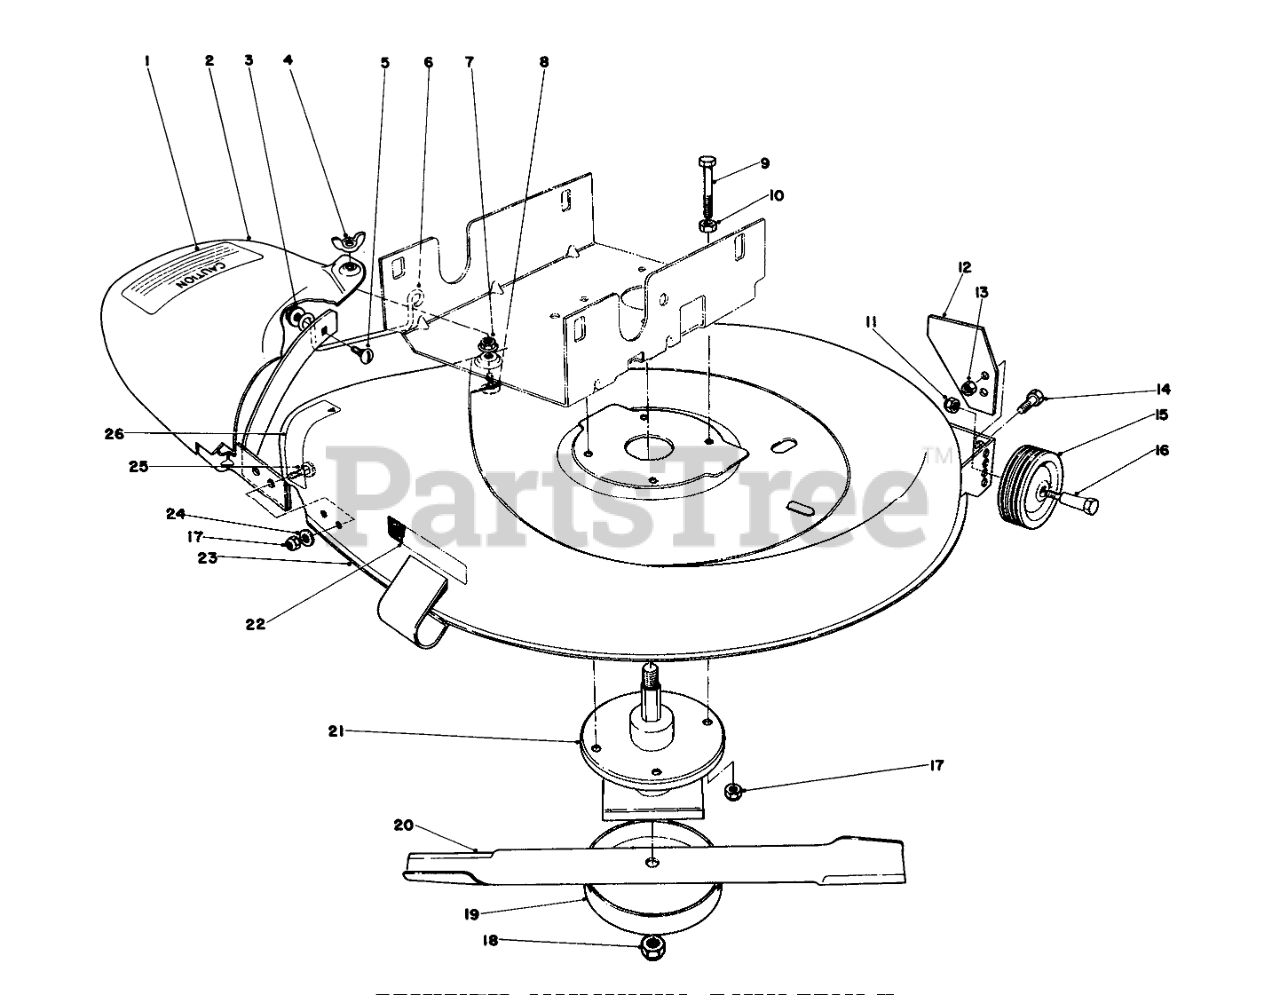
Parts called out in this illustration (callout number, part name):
1	Decal
2	DEFLECTOR WA R
3	NUT-LOCK, HHF
4	Wing Nut
5	SCREW-CARRIAGE
6	Bracket Foot Guard
7	PAL NUT
8	Carriage Bolt
9	SCREW-HH
10	NUT-JAM
11	Nut
12	Deck Stop
13	NUT-LOCK, CONE
14	SCREW-HH
15	Wheel
17	NUT-LOCK, CONE
19	Cup
20	Blade
21	Mower Spindle
22	Decal-Deck Inst.
23	HOUSING WA R
24	WASHER-FLAT
25	BOLT-CARR
26	Decal Housing
